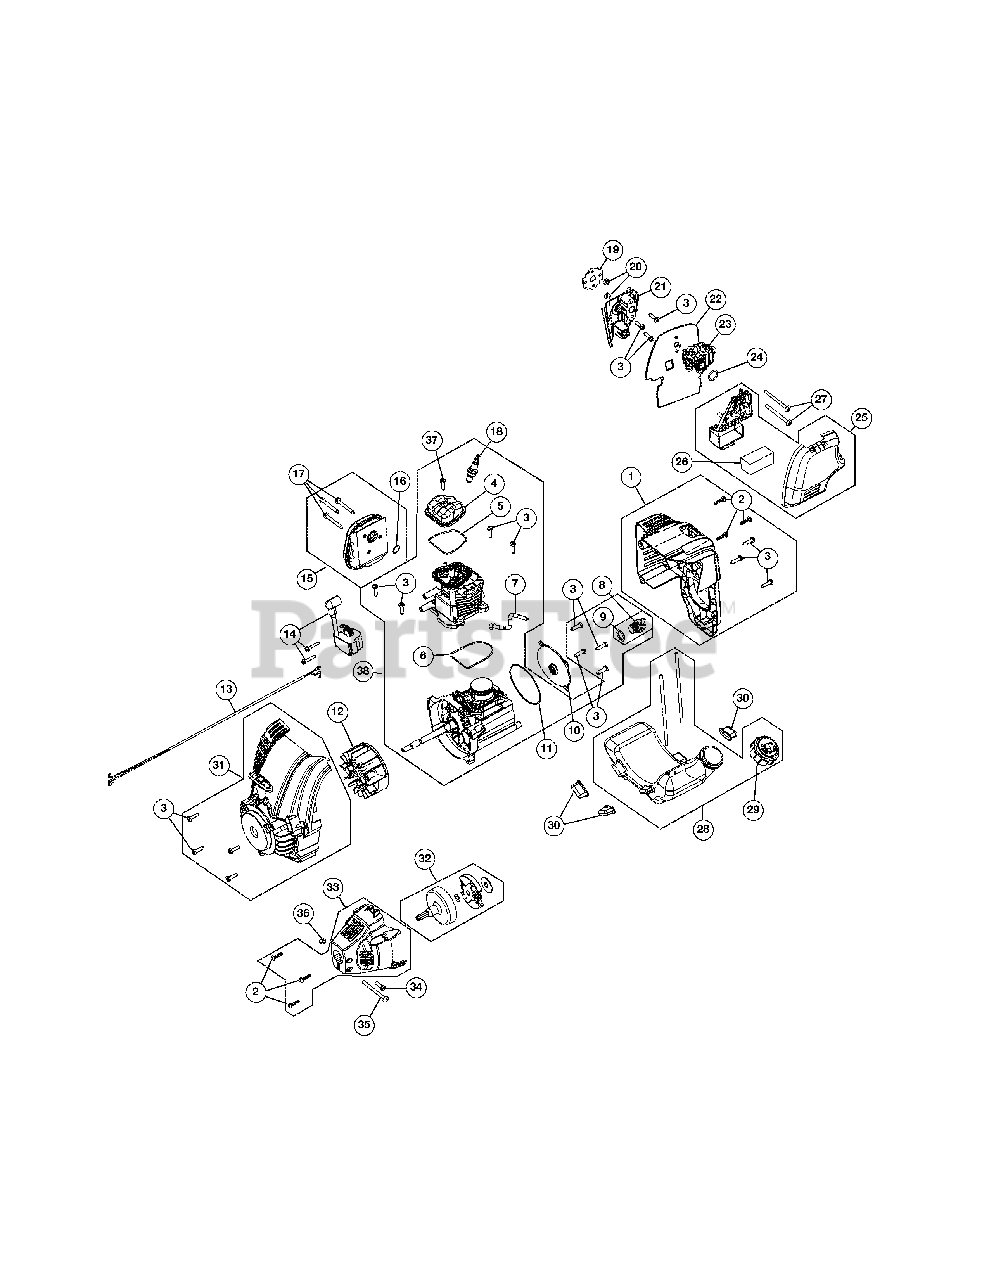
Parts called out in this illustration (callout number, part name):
1	Engine Cover Assembly (Incl. Ref No. 2 & 3)
2	Cover Screw
3	Screw
4	Rocker Cover
5	Rocker Cover O-Ring
6	Cylinder O-Ring
7	Breather Hose
8	Oil Plug (Incl. Ref No. 9)
9	Oil Plug O-Ring
10	Crankcase Cover
11	Crankcase Cover O-ring
12	Flywheel Assembly
13	Lead Wires
14	Module Assembly
15	Muffler Assembly (Incl. Ref No. 16 & 17)
16	Muffler Gasket
17	Muffler Screw
18	Spark Plug
19	Insulator Gasket
21	Insulator
22	Carburetor Gasket
23	Carburetor w/Primer
24	Air Cleaner O-Ring
25	Air Cleaner Cover Assembly (Incl. Ref No. 32)
26	Air Filter
28	Fuel Tank Assembly w/Fuel Lines (Incl. Ref No. 35)
29	Fuel Cap
30	Fuel Tank Pads
31	Starter Housing Assembly (Incl. Ref No. 3)
32	Clutch Assembly
33	Clutch Cover (Incl. Ref No. 2)
34	Anti-Rotation Screw
35	Clamp Screw
37	Rocker Cover Screw
38	Shortblock Assembly
